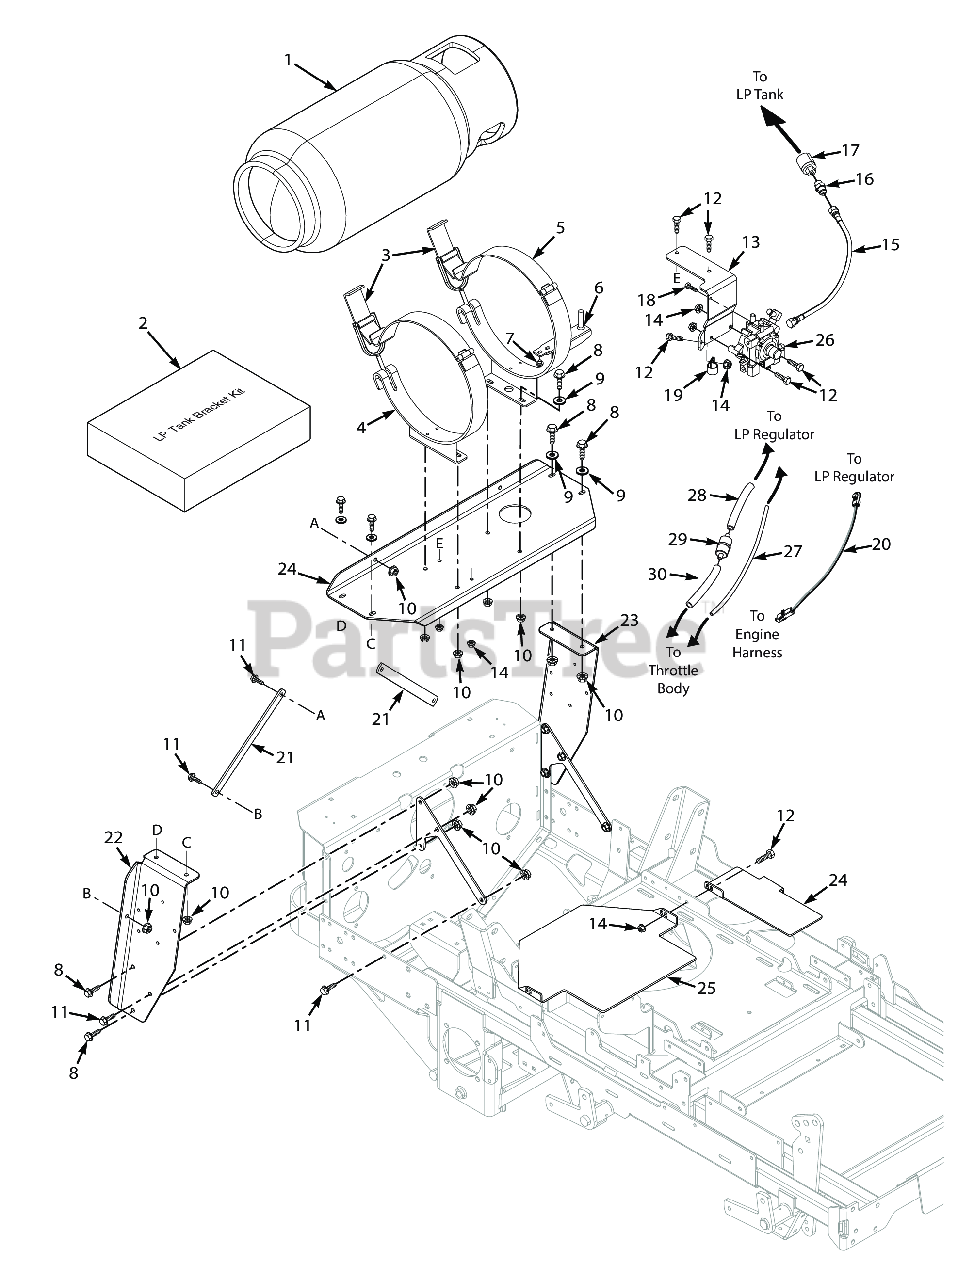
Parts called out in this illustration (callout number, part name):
1	LP Tank - Vapor
2	Mounting Bracket Kit
3	Handle, LP Tank Mounting Bracket
4	Mounting Bracket, LP Tank Rear
5	Mounting Bracket, LP Tank Front
6	LP Tank Locating Bracket
7	Bolt, Hex Head 1/4-20 x 3/8" Locking
8	Bolt, Hex Head, 3/8-16 x 1 Gr. 5
9	Flatwasher, 3/8" Special (.391 x .938 x .105)
10	NUT, 3/8-16 SERRATED FLANGE HEX HEAD
11	Bolt, Hex Head, 3/8-16 x 3/4"
12	BOLT, SERRATED FLANGE HEX HEAD 5/16-18 X 3/4"
13	Mounting Bracket, Regulator
14	Nut, Serrated Flange 5/16-18 (Right Front Engine Mounting, Briggs and Kohler Only)
15	LP Fuel Line, 17"
16	Adapter Fitting, 9/16-18 SAE x 1/4" Pipe
17	LP Quick Coupler
18	BOLT, HEX HEAD, 1/4-20 X 3/4 GR.5
19	Clamp, Cable 3/4" ID.
20	Adapter, Wire Harness
21	Brace, Engine Mounting
22	Mounting Bracket, Tank Support - RH
23	Mounting Bracket, Tank Support - LH
24	Cover, Fuel Tank Hole
25	Cover, Fuel Tank
26	LP Regulator
27	Hose
28	Hose
29	Fuel Filter
30	Hose
